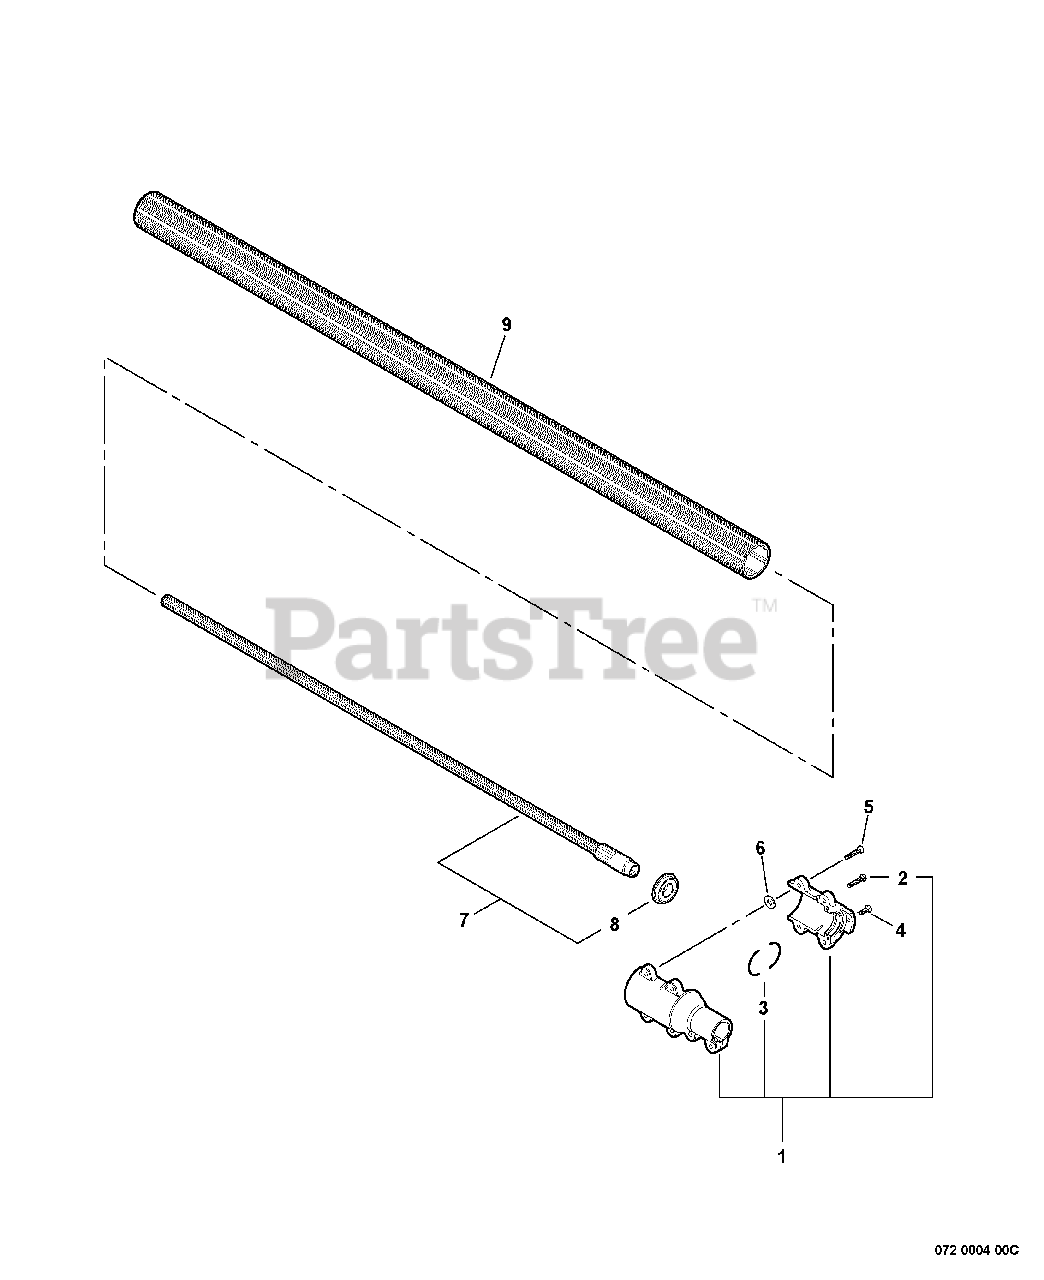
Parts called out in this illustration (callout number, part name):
1	COUPLING ASSY
2	SCREW - 5X20
3	CUSHION
4	SCREW - 5X14
5	SCREW - 5X20
6	WASHER - 5
7	DRIVESHAFT ASSY - LOWER
8	BEARING, BALL - 6002
9	PIPE, MAIN - ORANGE
